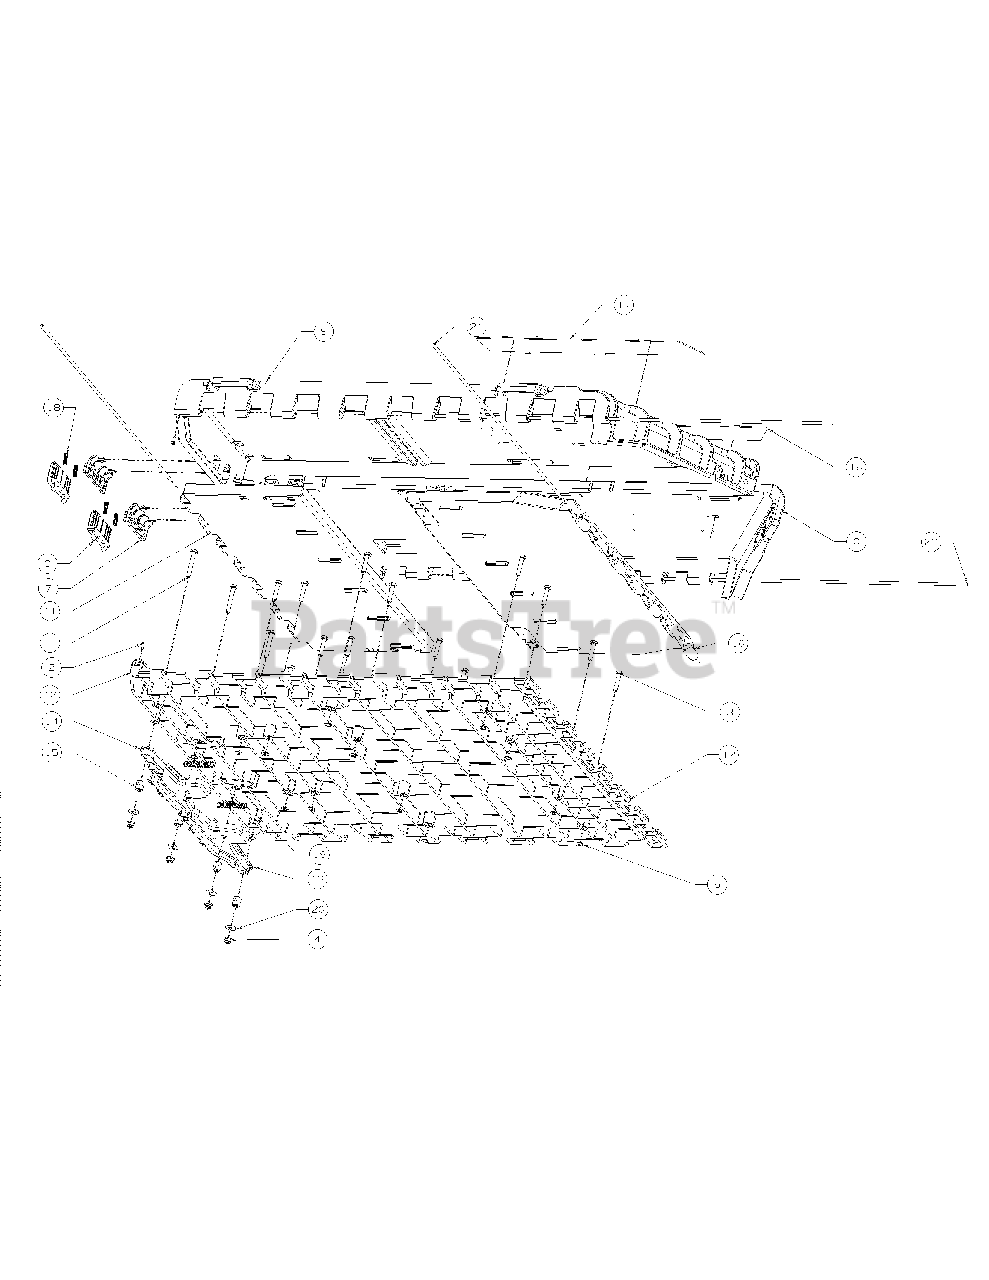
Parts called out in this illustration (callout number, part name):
1	Screw-Hex 5/16-18
2	Screw-Plastite
3	Screw-Hex Cap
4	Nut-Flglk 5/16-18
6	Latch-Panel
7	Latch:Retaining-Panel
8	Panel, SD LH
9	Panel, SD RH
10	Panel, Tail Gate RR
11	Panel, SD Front
12	Panel, Base
13	Lever:Release-Rh Door
14	Lever:Release-Lh Door
15	Spacer-Lever
16	Plate, RH Logo
17	Plate, LH Logo
18	Spring:Compression
19	Spring:Compression
20	Washer-Fl
21	Rod:Hinge .25 X 27.7
22	Rod:Hinge .25 X 36.8
